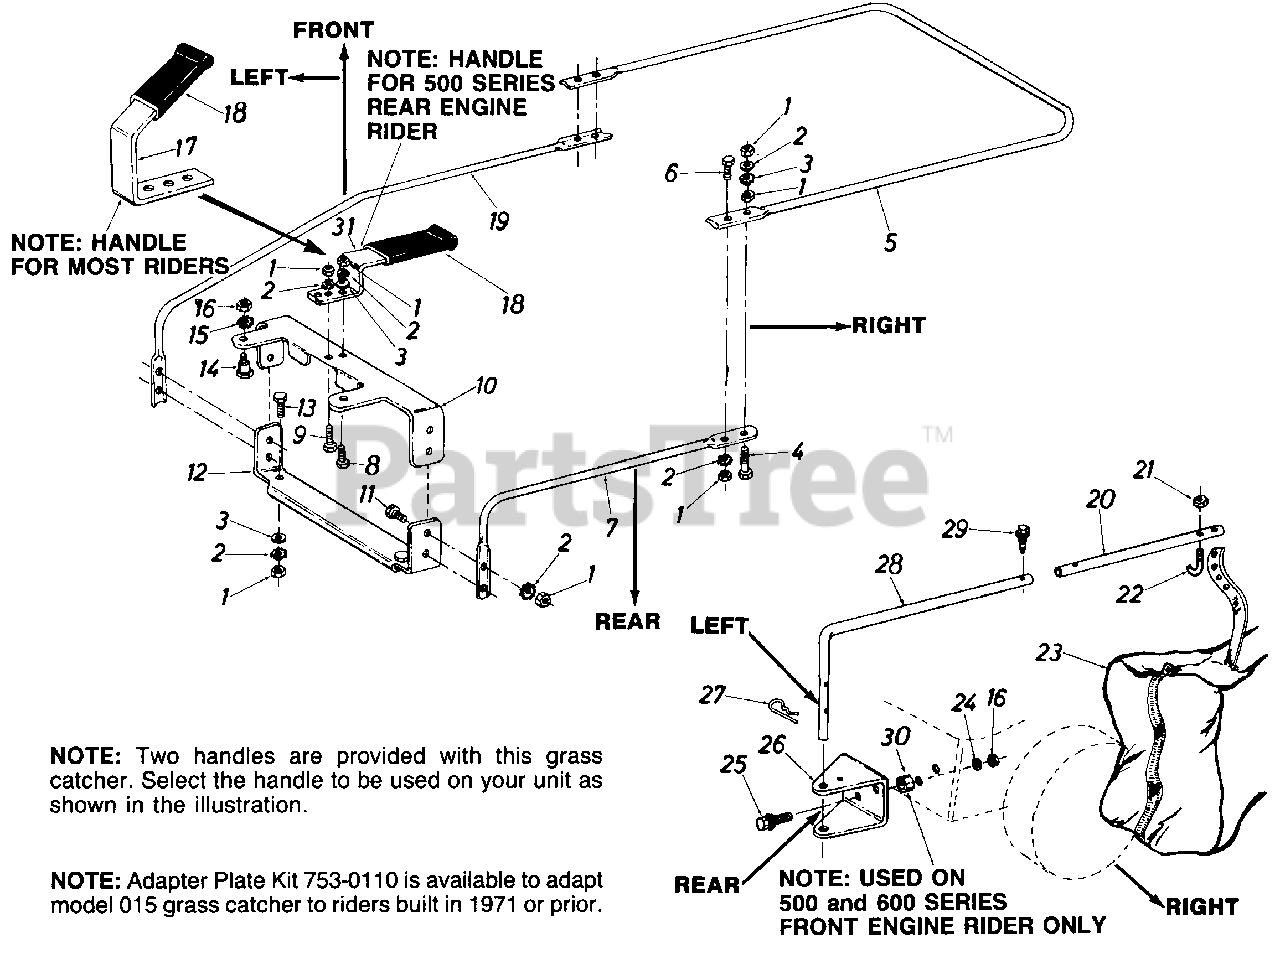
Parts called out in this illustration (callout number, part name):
1	Hex Nut 1/4-20 Thd.
2	Ext. L-Wash. 1/4" I.D.
3	Fl-Wash. .281" I.D. x .5" O.D.
4	Hex Bolt 1/4-20 x 1.5" Lg.
5	Upper Frame Half
6	Hex Bolt 1/4-20 x 1" Lg.
7	Lower Frame Tubing
8	Hex Bolt 1/4-20 x .62" Lg.
9	Hex Bolt 1/4-20 x .85" Lg.
10	Upper Opening Support
11	Hex Bolt 1/4-20 x 1" Lg.
12	Lower Opening Support
13	Hex Bolt 1/4-20 x .50" Lg.
14	Shld. Bolt .437 Dia. x .350
15	Ext. L-Wash. 5/16" I.D.
16	Hex Nut 5/16-18 Thd.
19	Lower Frame Arm
23	Grass Catcher Bag
24	L-Wash. 5/16" I.D.
25	Hex Sems Bolt 5/16-18 x .75" Lg.
26	Hitch Bracket
27	Internal Cotter Pin 518" Dia.
28	Lower Holding Arm
29	Hex Self-Tap .50" Lg.
30	Spacer
31	Handle
